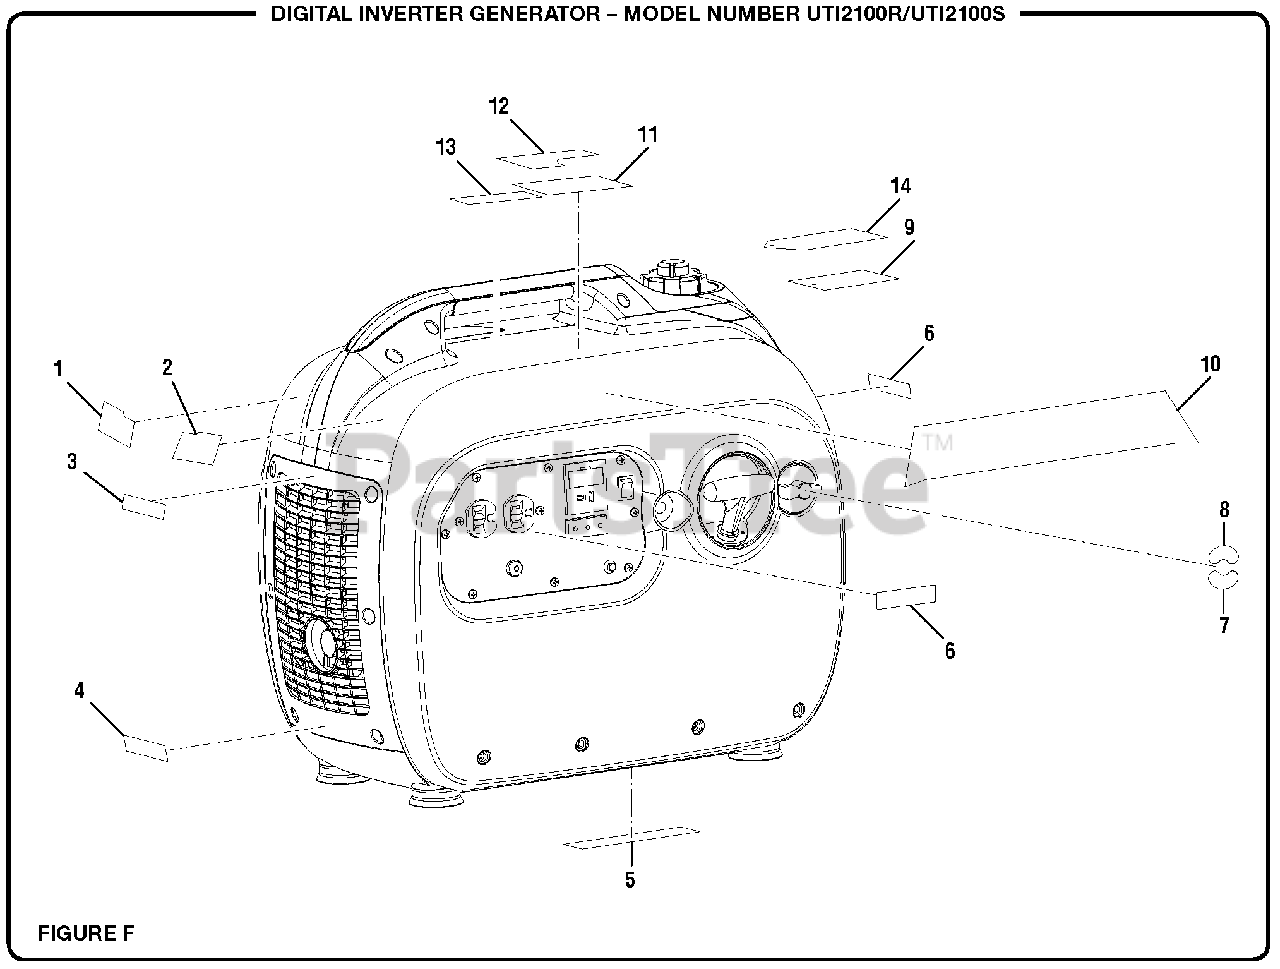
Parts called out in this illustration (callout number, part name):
1	Fire Distance Label
2	Lubricant Label
3	Hot Surface Label
4	Combustion Label
5	Data Label (UTi2100R)
5	Data Label (UTi2100S)
6	Logo Label
8	OFF Label
9	Vented Fuel Cap Hangtag
10	Performance Label
11	Danger Icon Label
12	Start Label
13	CPSC Label
14	Danger Hangtag
